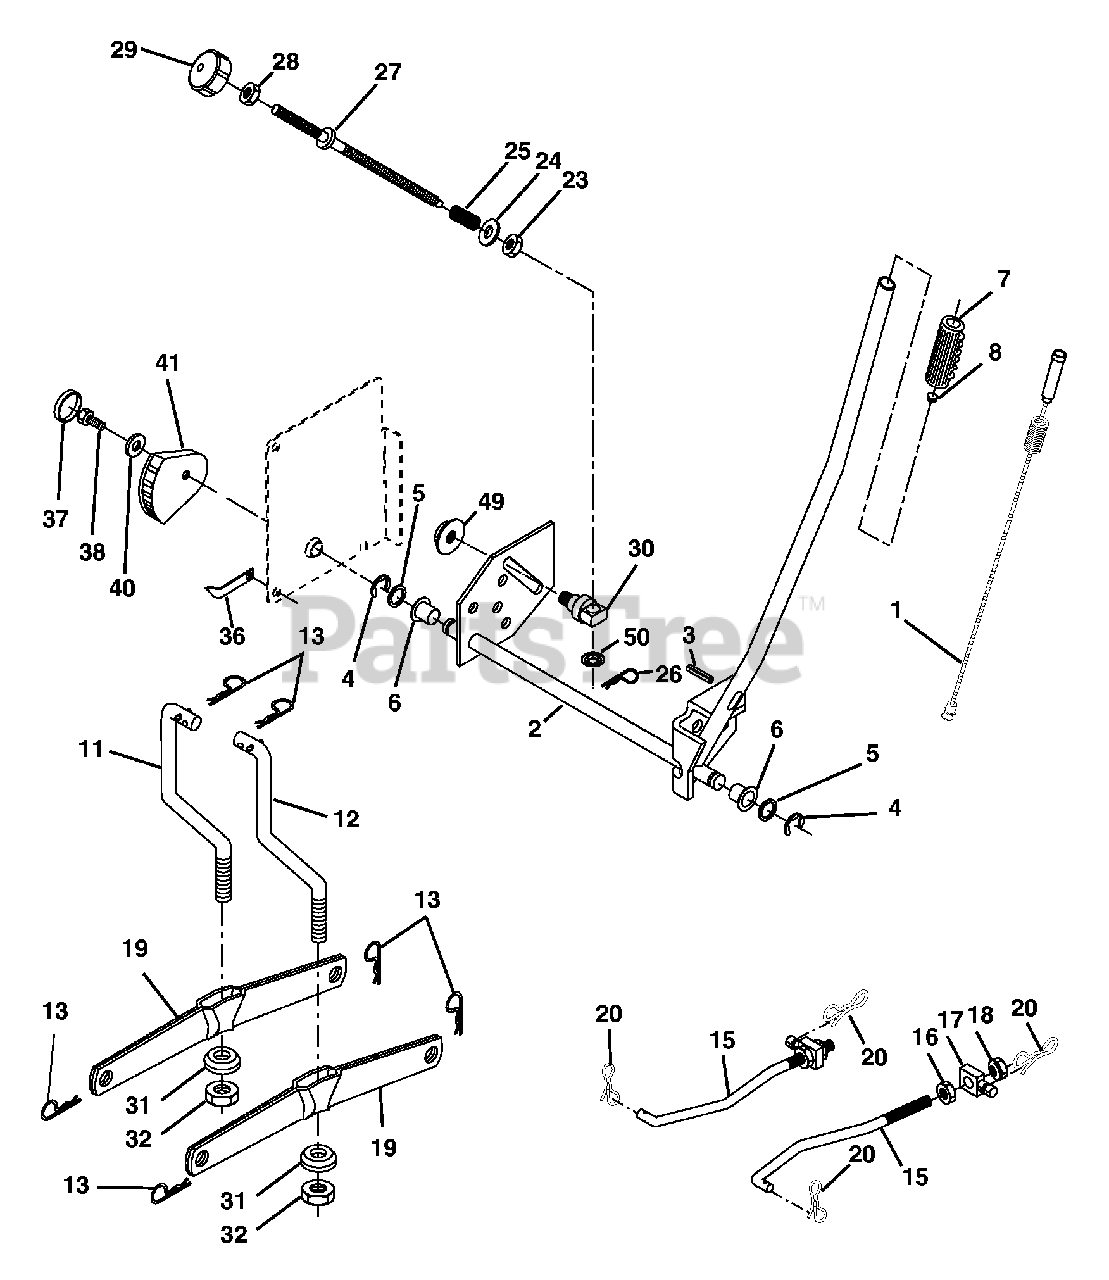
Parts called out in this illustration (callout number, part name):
1	Plunger Asm.
2	Shaft Asm Lift RH w/Inf
3	Pin Groove 2"
4	E Ring #5133-62
5	Washer 21/32 x 1 x 21 Ga.
6	Bearing Nylon Blk 629 Id
7	Grip Handle
8	Button Plunger
11	Link Lift LH Fixed Length
12	Link Lift RH Fixed Length
13	Retainer Spring
15	Link Front
16	Nut Jam Hex 1/2-13 unc
17	Trunnion
18	Nut Lock W/Wsh 1/2-13 unc
19	Arm Suspension Rear
20	Pin Cotter 7/16 Bow Tie Lock
23	Nut Special
24	Washer 13/32 x 5/8 x 16 Ga.
25	Spring Infin. Height
26	Retainer Clip
27	Rod Adjust Lift
28	Nut Hex Jam 3/8-16 unc
29	Knob Infin. 3/8-16 unc
30	Trunnion Infi. Height
31	Bearing Pvt Lift
32	Nut Crownlock 3/8 - 24
36	Pointer Height Indicator
37	Plug Hole
38	Screw 5/16-18 x 1
40	Washer 11/32 x 1-1/2 10 Ga.
41	Indicator Height
49	Nut Hexflange Lock
50	Nut Push
